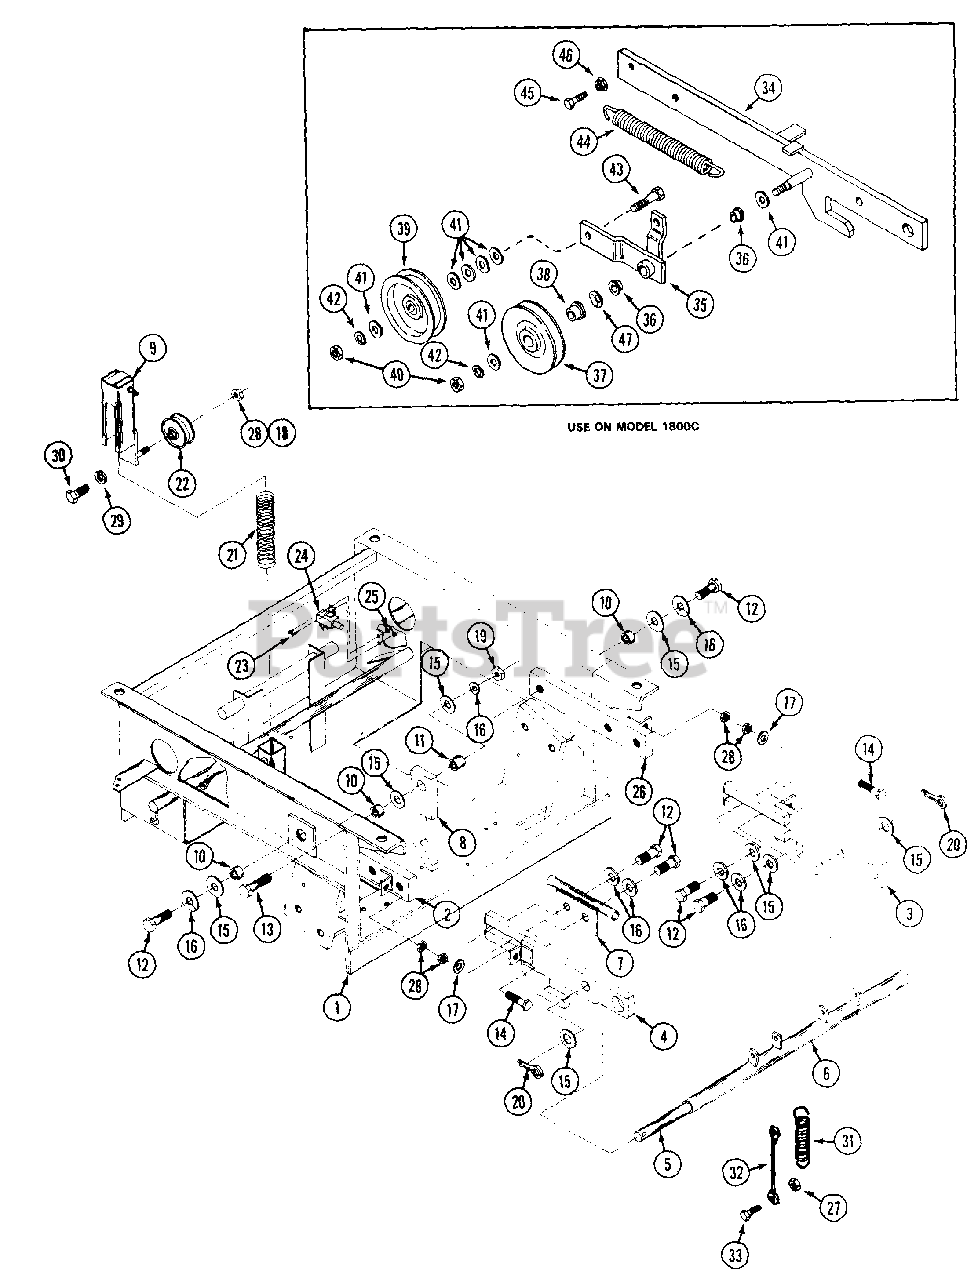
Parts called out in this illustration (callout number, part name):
1	BASE
2	ARM - deck lift R.H.
3	ARM - front L.H
4	ARM - front R.H.
5	PIN - cross bar
8	LOCK - forward nose down
9	TUBE - drive idler
10	BUSHING - deck lift arm (3/8" long)
11	BUSHING - pivot (1/2" long)
12	BOLT - 1/2"-13 x 1-1/4"
13	BOLT - 1/2"-13 x 2-1/4"
14	BOLT - 3/8"-16 x 3"
15	WASHER - 1/2"
16	LOCKWASHER - 1/2"
17	WASHER - 3/8"
18	NUT - flange lock 3/8"-16
19	NUT - 1/2"-13
20	PIN - cotter 1/8" x 1"
21	SPRING - idler tension
22	PULLEY - idler 2-1/4" O.D.
23	SCREW - machine #10-32 x 5/8"
24	SWITCH - safety
25	NUT - lock #10-32
26	ARM - deck lift L.H.
27	NUT - lock 1/4"-20
28	NUT - 3/8"-16
29	LOCKWASHER - 3/8"
30	BOLT - 3/8"-16 x 2-1/2"
31	SPRING - lift assist
33	BOLT - 1/4"-20 x 1"
34	ARM - deck L.H.
34	ARM - deck R.H.
35	ARM - idler
36	BEARING - flange
37	PULLEY - "V" idler
38	BUSHING - pulley
39	PULLEY flat
40	NUT - 3/8"-16
41	WASHER - 3/8"
42	LOCKWASHER - 3/8"
43	BOLT - 3/8"-16 x 2"
44	SPRING - extension
45	BOLT - 5/16"-18 x 1"
46	NUT - 5/16"-18 flange lock
47	WASHER - spring
